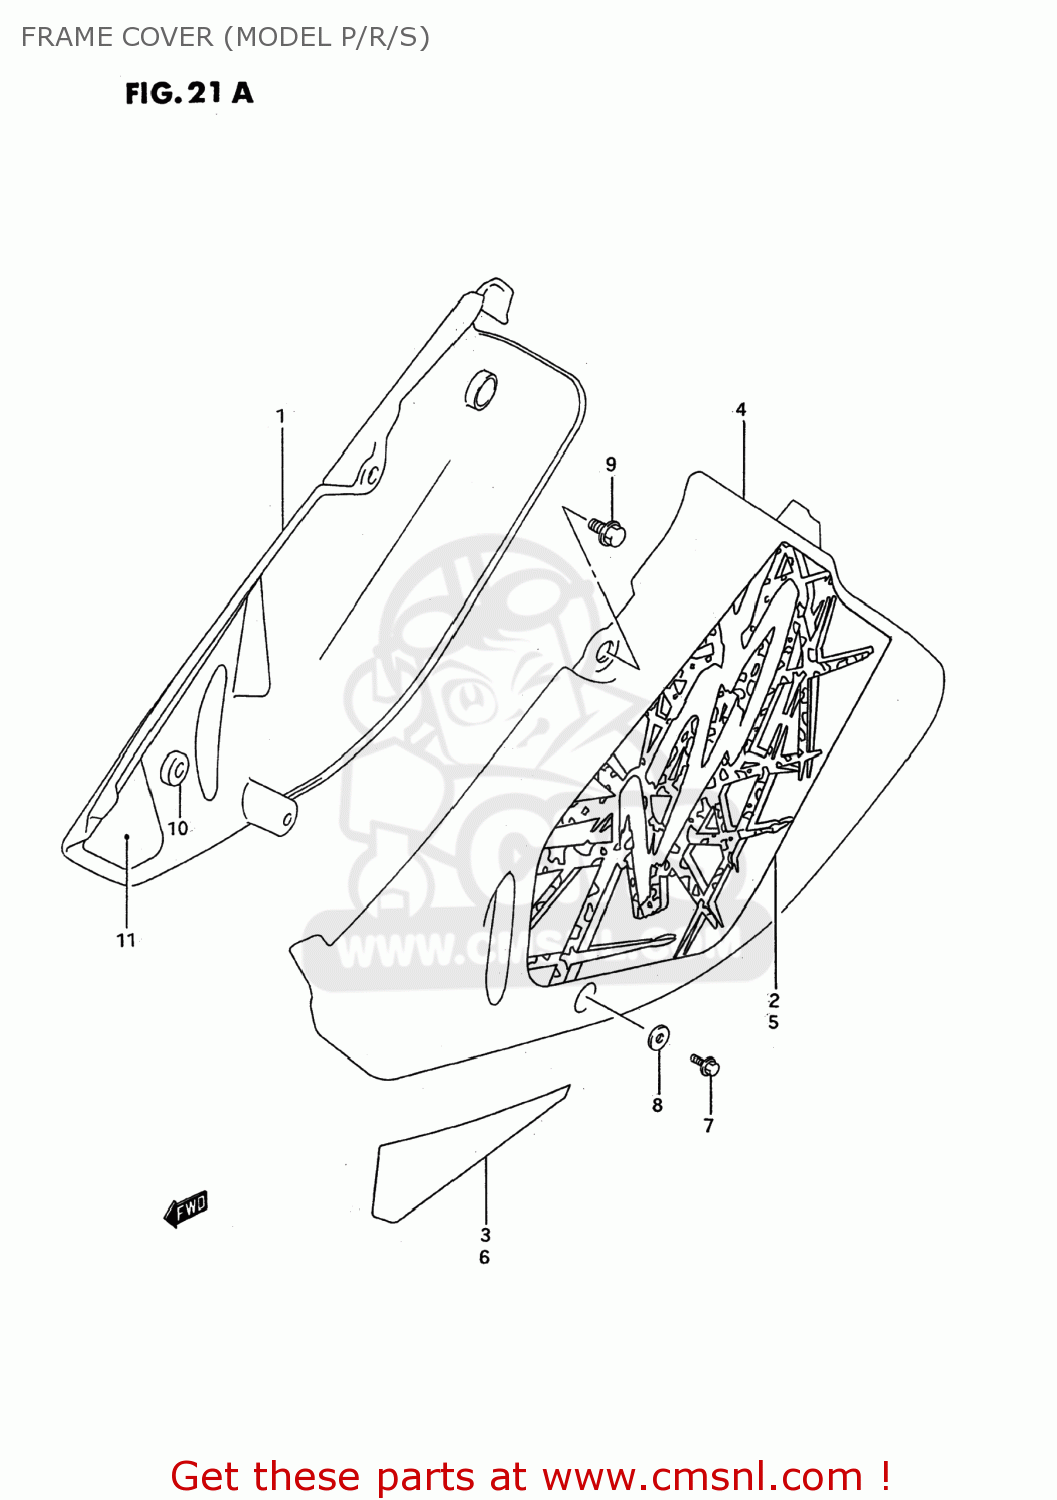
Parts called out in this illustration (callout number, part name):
1	COVER,FRAME,RIGHT
2	EMBLEM,FRAME COVER,RIGHT
3	EMBLEM,FRAME COVER,RIGHT
4	COVER,FRAME,LEFT
5	EMBLEM,FRAME COVER,LEFT
6	EMBLEM,FRAME COVER,LEFT
7	BOLT
8	WASHER
9	BOLT
10	CUSHION
11	SHIELD,FRAME COVER,RIGHT H
